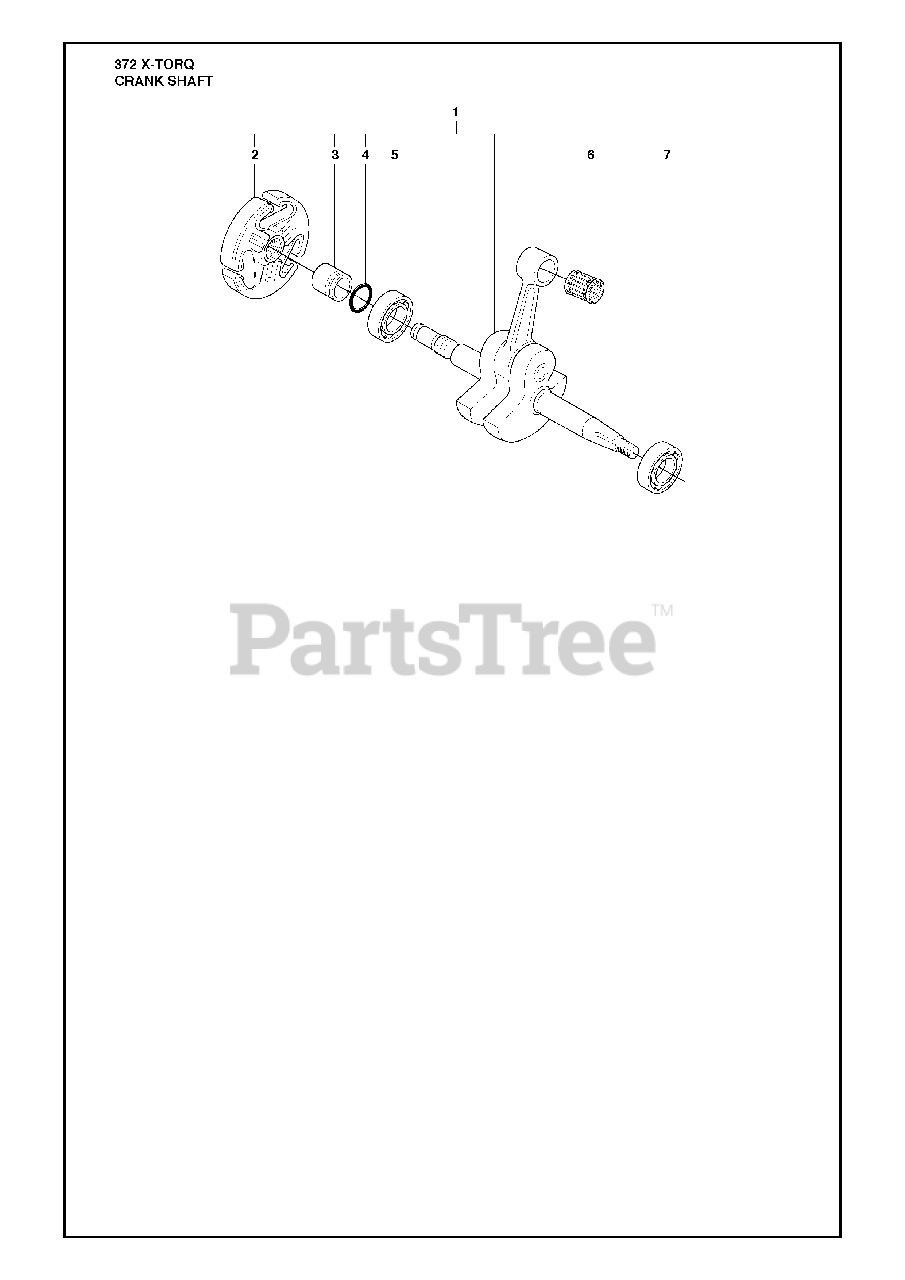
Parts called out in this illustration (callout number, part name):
1	CRANKSHAFT COMPLETE
2	CLUTCH
5	BALL BEARING-6202-C3 SKF
6	SUPPORT BUSHING
7	BALL BEARING-6202-C3 SKF
